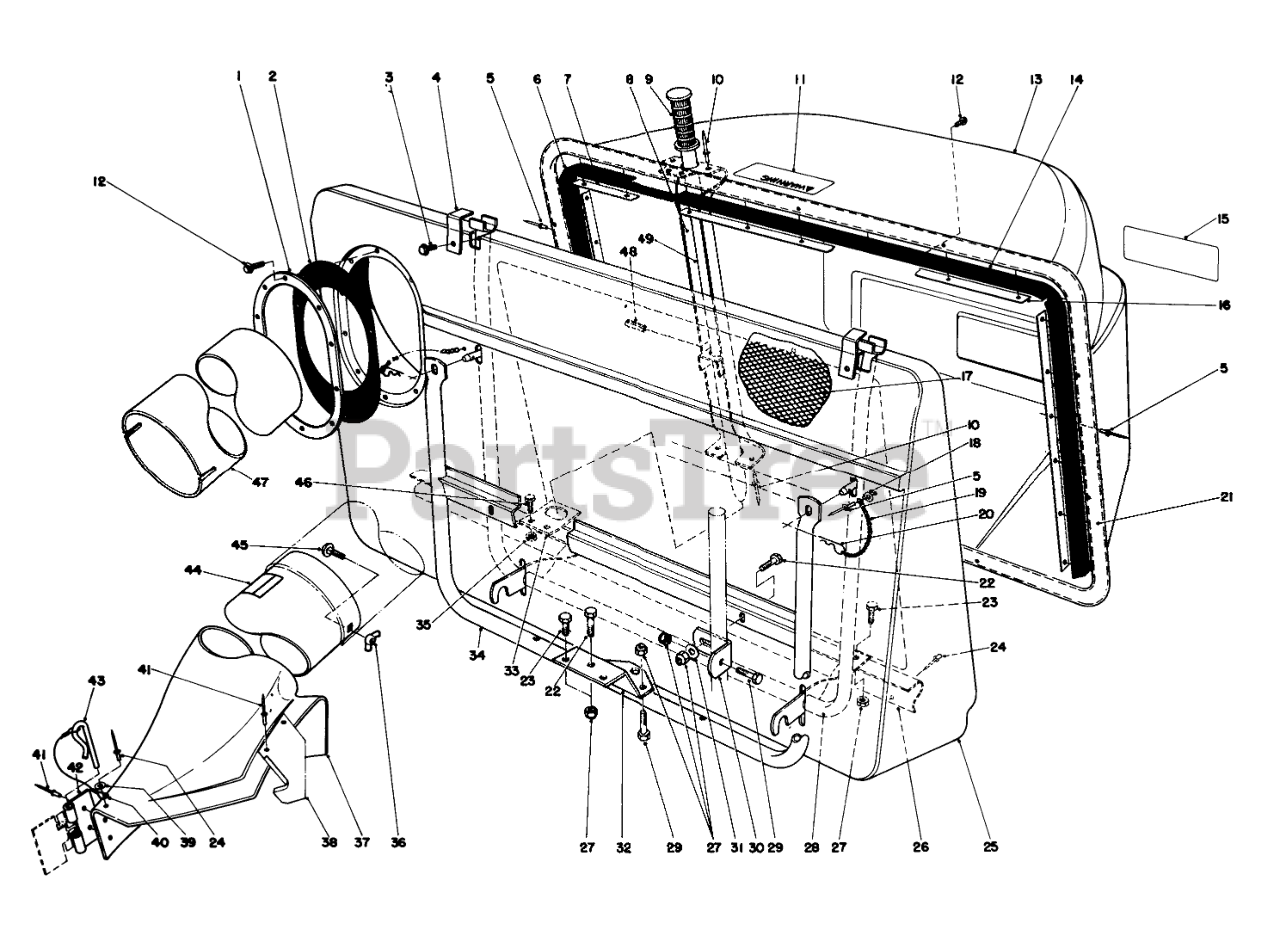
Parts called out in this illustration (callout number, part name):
1	RING-RETAINING
2	RING-RETAINER, RUBBER
3	Hex Hd. Tap Screw
4	RETNR PIVOT BRKT
6	RH BAG SEAL
7	RETNR TOP EXT.
8	DUMP HDLE CHANL WA
11	Decal Warning
12	SCREW-HWHTF
13	REAR GRASS BASKET
14	Seal-Bag LH.
15	EASY EMPTY BAG DECAL
16	BAG RETNR EXT.
17	Screen Bag
18	WASHER
19	10 LINK CHAIN W/O HOOK
20	PIN-HAIR
21	BAG SUPT ASM FRM
22	SCREW-HH
23	SCREW-HH
24	RIVET-BLIND
25	Bag Front
26	FRAME SUPT BRKT B
27	NUT-LOCK, CONE
28	Bag Frame
29	SCREW-HH
30	Bracket Mtg. Grass Catcher
31	WASHER-PLAIN
32	MTG PLATE B
33	Hanger-Frame Lower
34	BAG SUPPORT WA
35	NUT-LOCK, CONE
36	NUT-WING SPECL
37	Chute Assembly (Incl. Ref. #24, 38-44)
38	CHUTE SUPT BRKT
39	WASHER-PLAIN
40	LANYARD
41	RIVET-BLIND
42	BRACKET-MOUNTING, CHUTE
43	PIN-LOCKING, CHUTE
44	DECAL-DANGER
45	BOLT-CARR
46	SCREW-HH
47	TUBE(ROUND&LONG)
48	PIN-ROLL
49	DUMP HANDLE ASM
